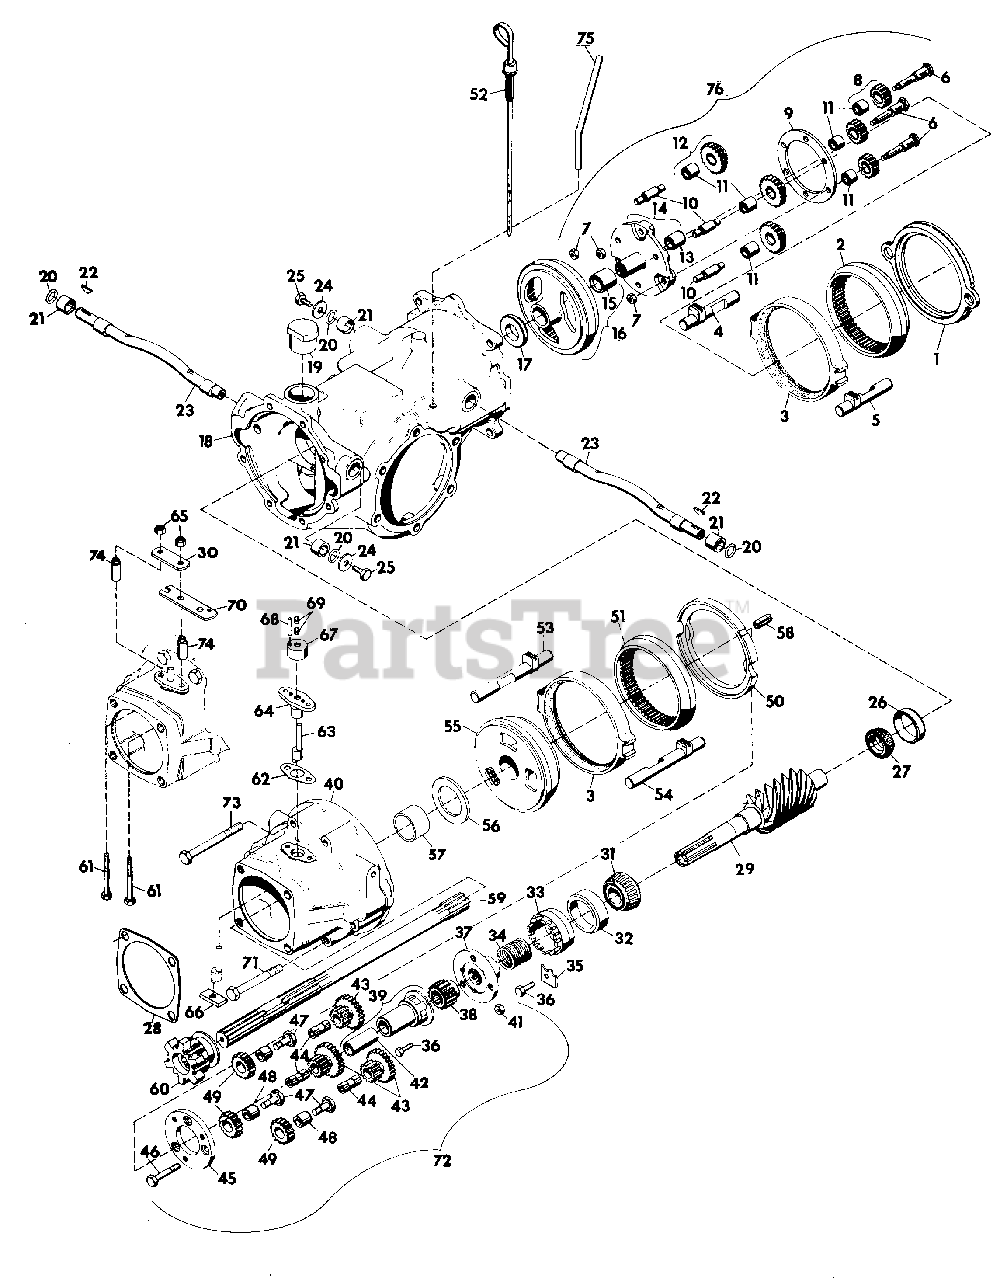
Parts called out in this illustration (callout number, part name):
1	SPACER, REAR
2	GEAR, REAR RING
3	ASSEMBLY, CLUTCH CUP
4	ROD, REAR CLUTCH SLIDE L.H.
5	ROD, REAR CLUTCH SLIDE R.H.
6	BOLT, ORBIT GEAR
7	NUT, LOCK 5/16-18 L.H. THD.
8	ASSEMBLY, EXTERNAL ORBIT GEAR
9	SPACER, PIN
10	PIN, HI-LO ORBIT GEAR
11	BUSHING .501X.627X.495
12	ASSEMBLY, INTERNAL ORBIT GEAR
13	BUSHING, .737X.877X.682
14	ASSEMBLY, PLANET GEAR CARRIER
15	BUSHING, 1.231X1.502X1.312
16	ASSEMBLY, RING GEAR AND BUSHING
17	PLATE, REAR THRUST
18	CHASSIS
19	PLUG, OIL FILLER
20	O-RING, .750X1.00
21	BUSHING, .750X1.002X.625
22	KEY, WOODRUFF .125X.625 HARD
23	SHAFT, ACTUATING
24	WASHER, FLAT .265X1.250X.063
25	BOLT, HEX 1/4-20X.50
26	CUP, ROLLER BEARING
27	CONE, ROLLER BEARING
28	GASKET, ATTACHMENT
29	WELDMENT, WORM SHAFT ASM 8 LEAD
30	SPACER, STRAP
31	CONE, ROLLER BEARING
32	CUP, ROLLER BEARING
33	NUT, BEARING ADJUSTMENT
34	SPACER, SPRING PIN PLATE
35	NUT, ADJUSTMENT
36	BOLT, HEX 1/4-20X.625
37	PLATE, FRONT PIN
38	GEAR, SUN PINION
39	ASSEMBLY, QUILL AND BUSHING
40	ASSEMBLY, ADVANCE CASTING
41	NUT, HEX 1/4-20
42	BUSHING, .875X1.000X2
43	GEAR, ORBIT
44	PIN, FWD-REV ORBIT GEAR
45	SPACER, FRONT PIN
46	BOLT, SPACER
47	BOLT, REVERSE IDLER
48	BUSHING, REVERSE IDLER
49	GEAR, REVERSE IDLER
50	CUP, GEAR
51	GEAR, INTERNAL
52	ASSEMBLY, DIP STICK
53	ROD, CLUTCH SLIDE L.H.
54	ROD, CLUTCH SLIDE R.H.
55	CONE, REVERSE GEAR
56	DISC, FRICTION
57	BEARING
58	PIN, ROLL
59	SHAFT, PINION
60	DOG, ATTACHMENT
61	BOLT, HEX 5/16-18X2.25
62	GASKET, SHIPPER SHAFT
63	SHAFT, SHIPPER
64	GUIDE, SHIPPER SHAFT
65	NUT, LOCK 5/16-18
66	BLOCK TRUNNION
67	BODY, SHIPPER SHAFT
68	PIN, SPRING .25X.75
69	SCREW, SET 3/8-16X.25
70	ARM, SHIFTER
71	BOLT, HEX 5/16-18X3.50 GR. 8
72	ASSEMBLY, FWD-REV PLANETARY
73	BOLT, HEX 5/16-18X3.25 GR. 8
74	SPACER, SHIPPER SHAFT GUIDE
75	GUIDE, DIPSTICK
76	ASSEMBLY, HI-LO PLANETARY
